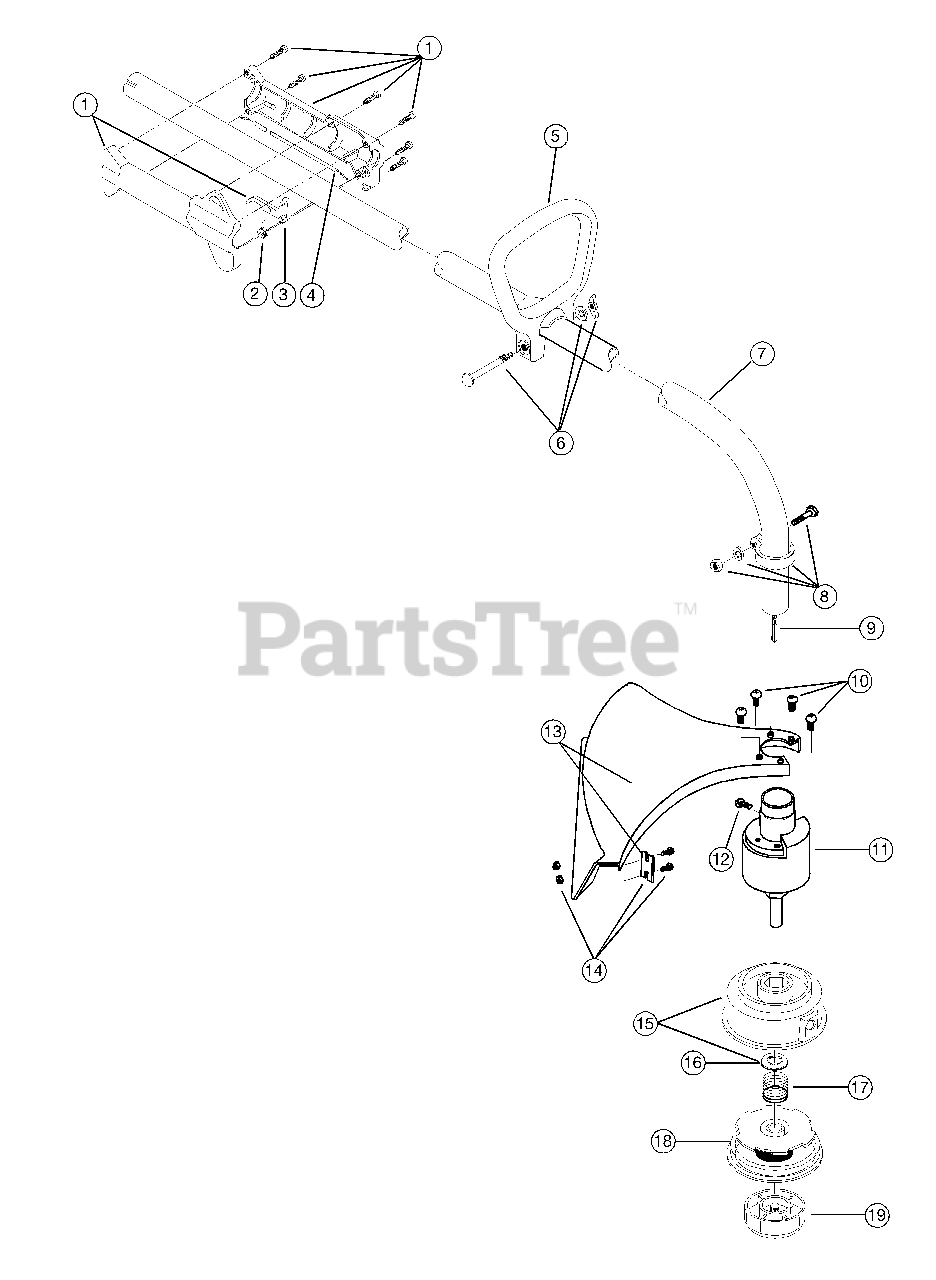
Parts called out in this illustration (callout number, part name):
1	Throttle Housing & Trigger Assembly
2	Throttle Trigger Spring
3	Throttle Trigger
4	Throttle Cable Assembly
5	D-Handle Assembly
6	D-Handle Hardware
7	Drive Shaft Housing Assembly
8	Lower Clamp Assembly
9	Flexible Drive Shaft
10	Shield Mounting Screw
11	Bushing Housing Assembly with Spool Shaft
12	Anti-Rotation Screw
13	Shield and Blade Assembly
14	Blade Assembly
15	Outer Spool Assembly
16	Retainer
17	Spring
18	Inner Reel
19	Bump Head Knob Assembly
